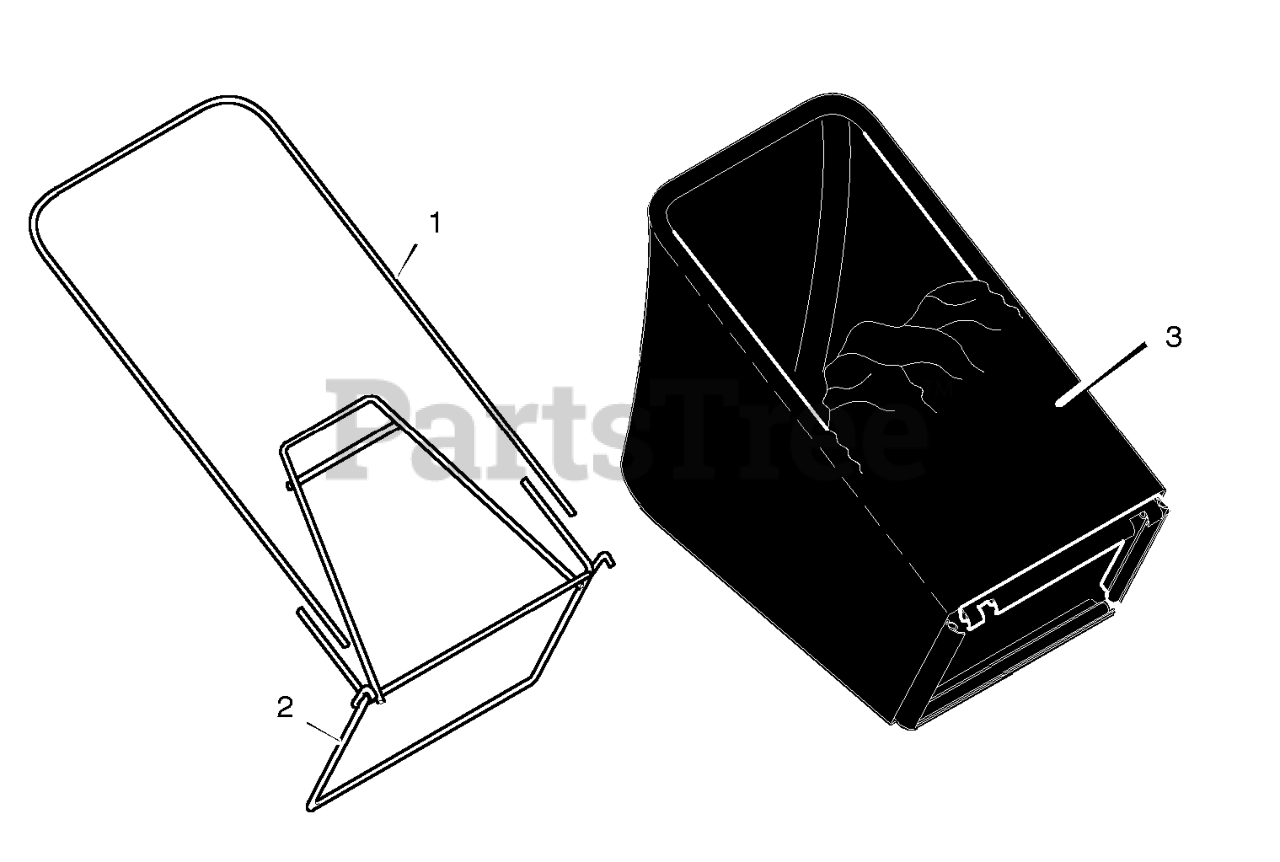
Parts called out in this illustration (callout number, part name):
1	Frame, Top
2	Frame Assembly
3	Bag, Cloth
